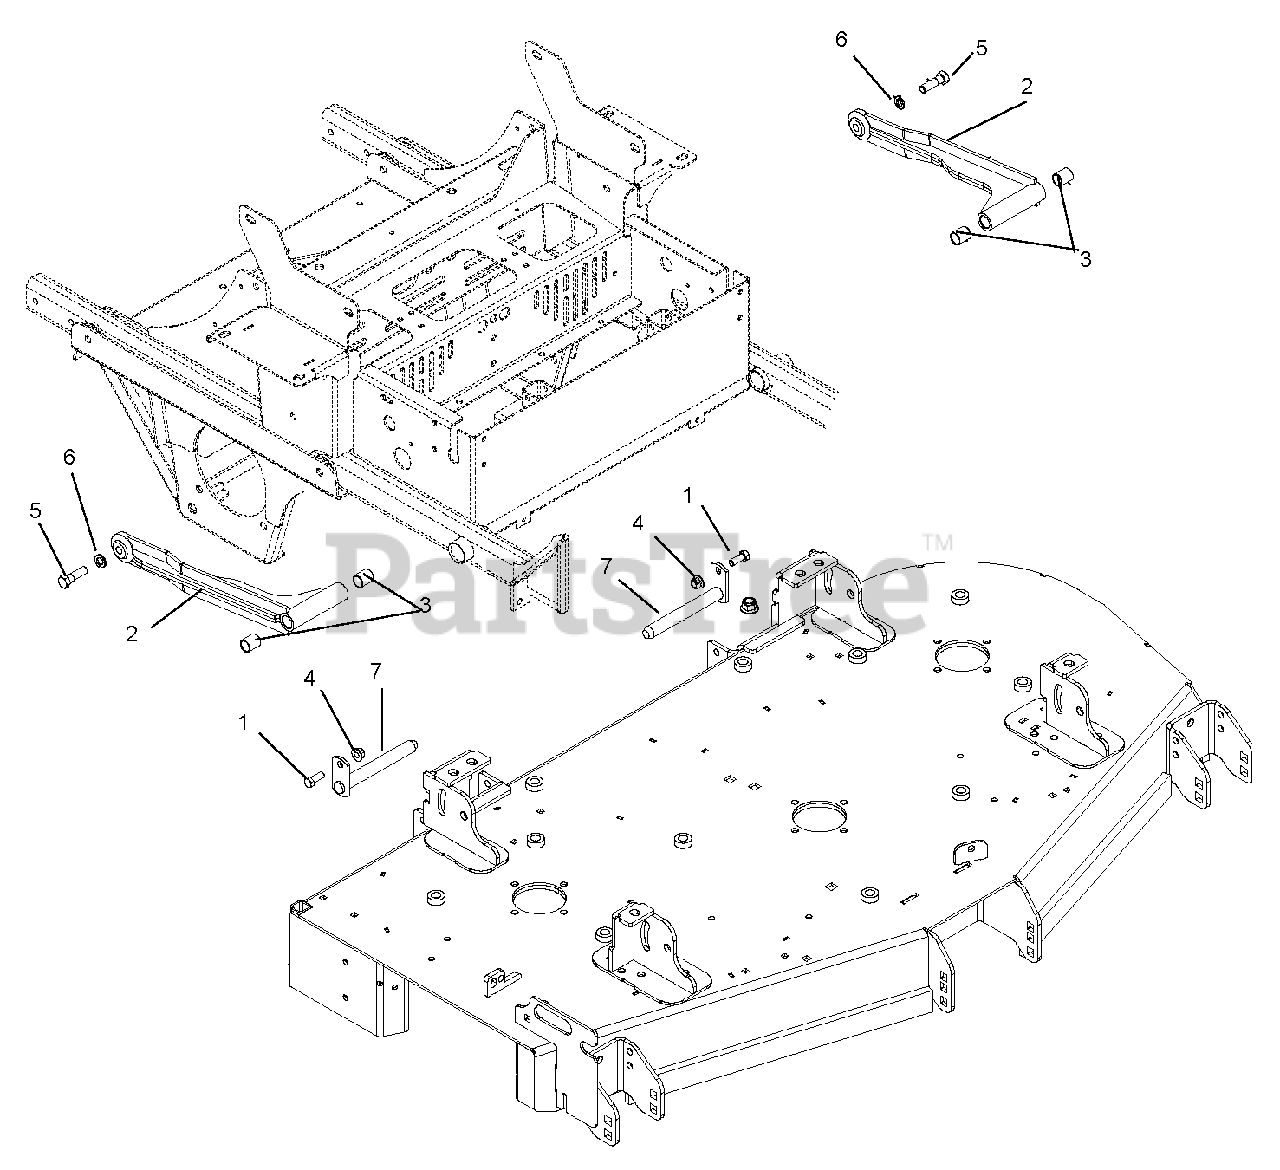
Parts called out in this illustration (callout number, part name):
1	Bolt, Hex .38-16 x 1.00 GR5 YWZC
2	Deck Stabilizer Arm – BLACK
3	Bearing, .75 x .875 x 1.00
4	Nut, Locking Nylon Flange .38-16
5	Bolt, Hex .50-13 x 1.75 GR5 EP80 YZ
6	Washer, Lock .50 x .125 REG YWZC
7	Weldment, Mower Mounting Pin
